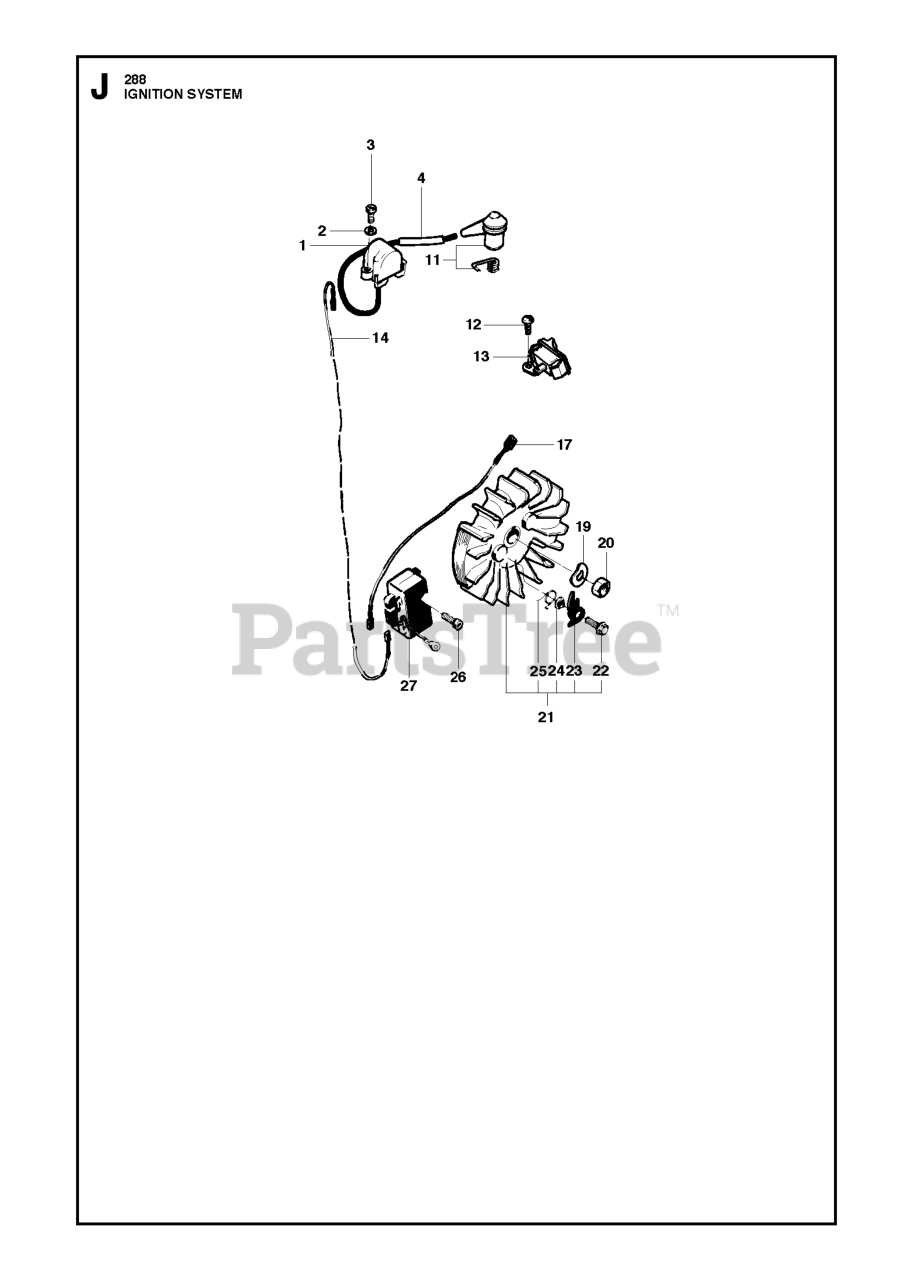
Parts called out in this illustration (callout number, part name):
1	IGNITION COIL
2	WASHER 4.2X9
3	SCREW MC6S 4X16
11	SPARK PLUG CONN. KIT
13	SWITCH ON/OFF
19	SPRING WASHER 10.5X18
21	FLYWHEEL ASSY
22	SCREW M5X14
26	SCREW MC6S 5X16
27	ELECTRONIC BOX
